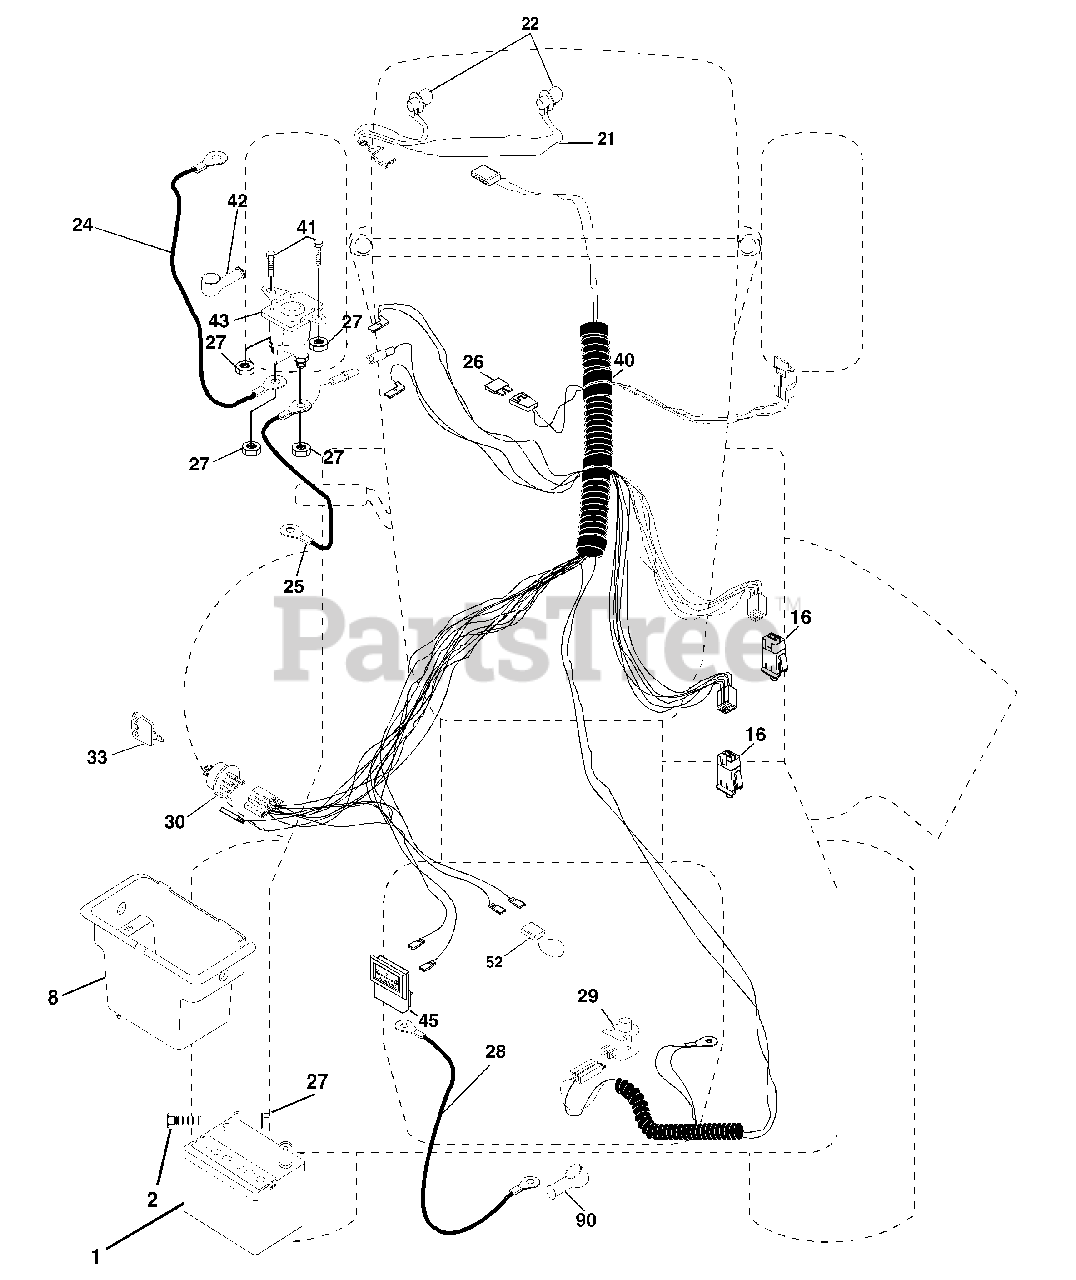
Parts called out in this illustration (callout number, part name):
1	Battery
2	Bolt Hex Hd 1/4-20unc X 3/4
8	Battery Box
16	Switch Interlock Push-In
21	Harness Socket Light
22	Bulb, Light # 1156
24	Cable Battery
25	Cable Battery 6 Ga Red w/16 wire
26	Fuse
27	Nut Keps Hex 1/4-20 Unc
28	Cable Ground 6ga 12 black
29	Switch Plunger Nc Gray
30	Switch Ign
33	Key Ign Molded Generic
40	Harness Ign
41	Bolt Fin Hex 1/4-20uncx 1/2
42	Cover Terminal Red
43	Solenoid
45	Ammeter Rectangular
52	Protection Loop
90	Cover Terminal
